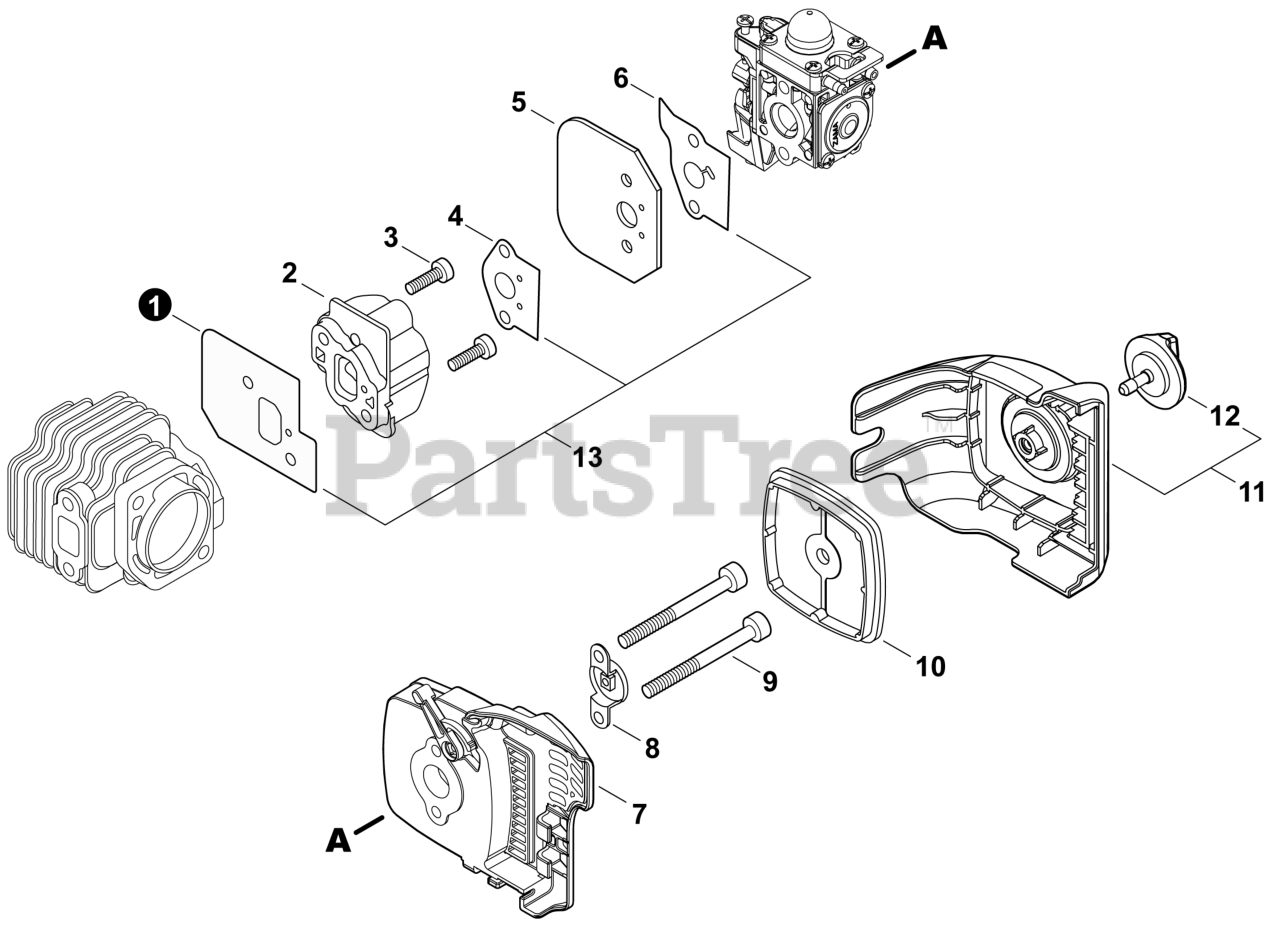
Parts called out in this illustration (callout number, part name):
1	GASKET, INTAKE
2	INSULATOR, INTAKE
3	BOLT, TORX 5×25
4	GASKET, INTAKE
5	PLATE, INSULATOR
6	GASKET, INTAKE
7	CASE, AIR FILTER
8	PLATE, PREVENT
9	BOLT, TORX 5×65
10	FILTER, AIR - DOUBLE LAYER
11	COVER SET, AIR FILTER
12	THUMBSCREW
13	GASKET KIT
